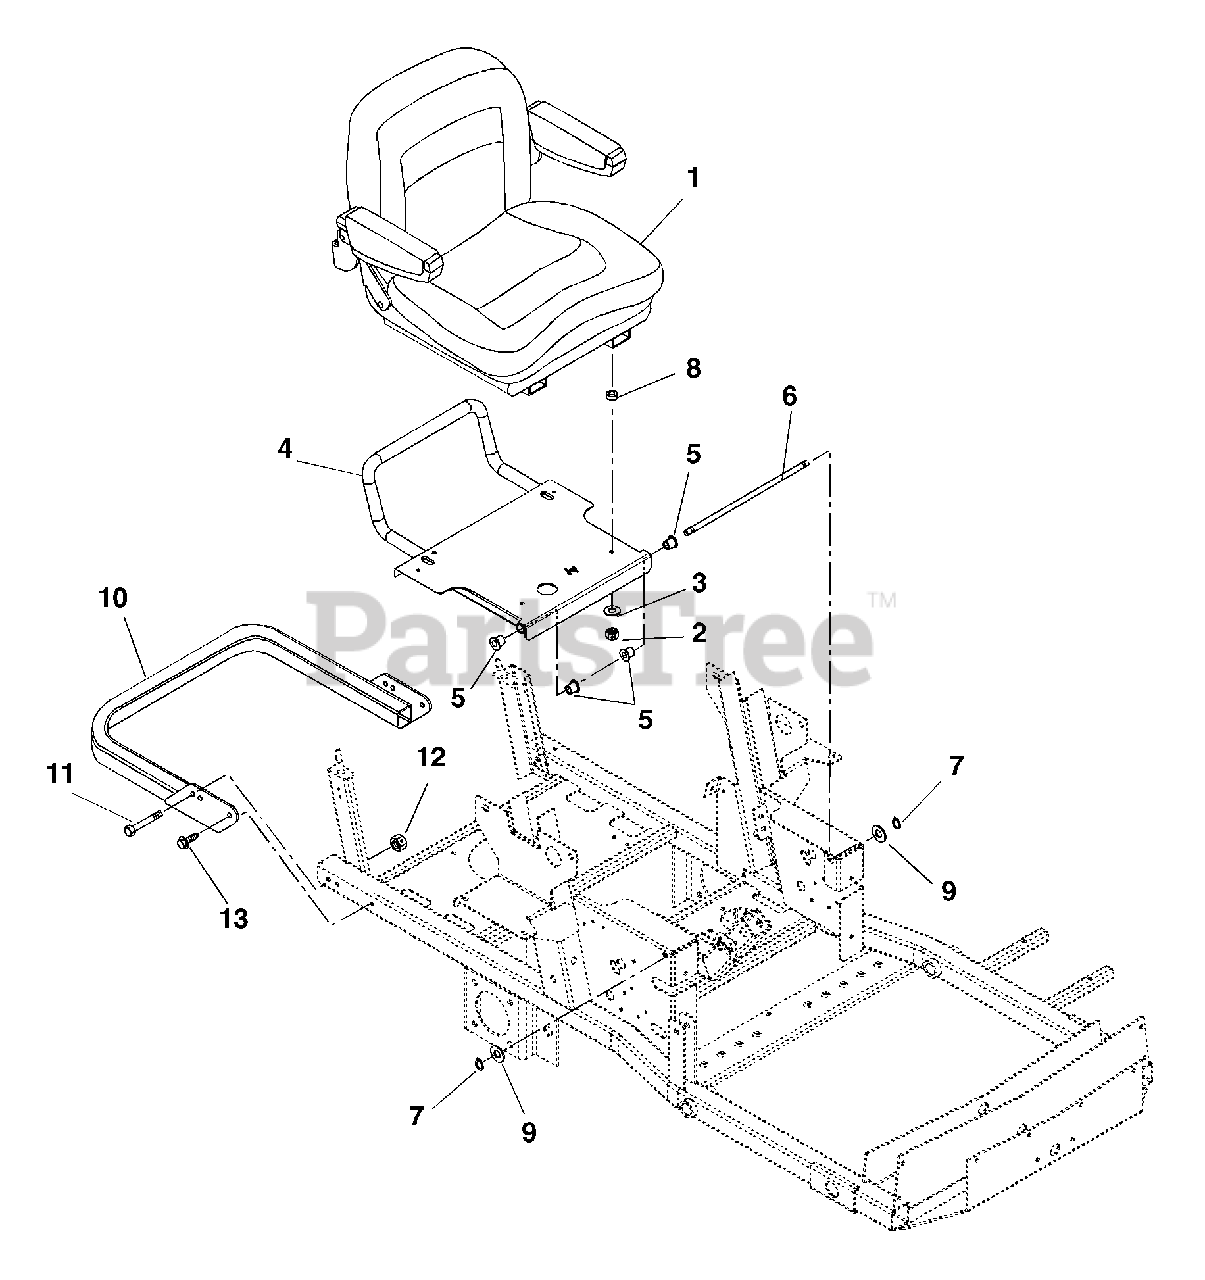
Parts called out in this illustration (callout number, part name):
1	Seat, MILSCO
2	Nut-Locking-Nylon .31-18
3	Washer-Flat-Steel .38 x .875 x .083
4	Weldment- Hood Frame
5	Bushing-Flange .515 x .750 x .745 x 1.00
6	Rod-Seat Frame Pivot
7	Ring-Retaining-External .50 x .05
8	Bushing-Sleeve .377 x .624 x .235
9	Washer-Flat-Steel .531 x 1.06 x .095
10	Bumper-Rear
11	Bolt-Hex .38-16 x 2.75 Grade 5
12	Nut-Locking-Center .38-16
13	Screw-Tapping .38-16 x .75 Hex Washer Head
